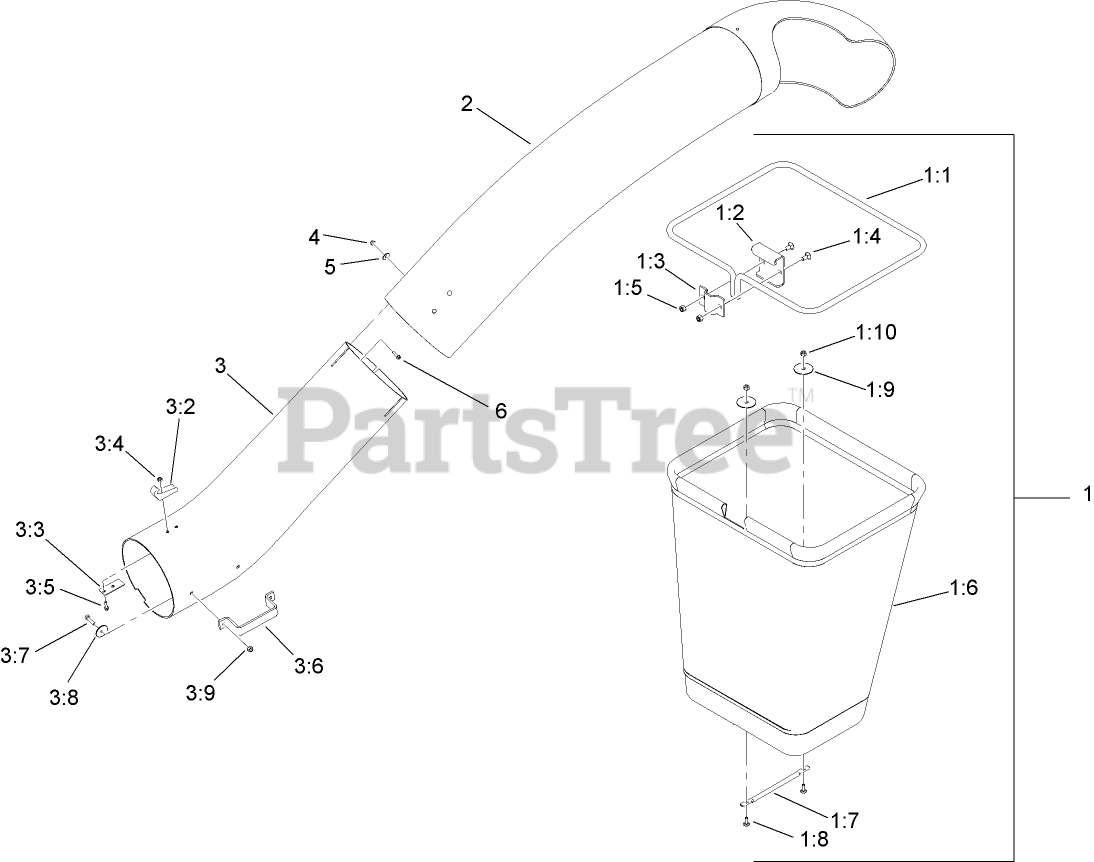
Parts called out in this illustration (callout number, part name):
1	Bag And Frame ASM
1:1	FRAME-BAG
1:2	HANGER-BAG
1:4	BOLT-CARR
1:5	NUT-LOCK, NI
1:6	Bag ASM
1:7	HANDLE-BAG
1:8	BOLT-CARR
1:9	WASHER
1:10	NUT-LOCK, NI
2	TUBE-UPPER
3	LOWER TUBE ASM
3:2	LATCH-CATCH
3:3	PLATE-BACKING
3:4	NUT-LOCK, NI
3:5	SCREW-HWH
3:7	SCREW-HH
3:8	WASHER-FLAT
3:9	NUT-LOCK, NI
4	NUT-LOCK, NI
5	WASHER-FLAT
6	SCREW-HWH
